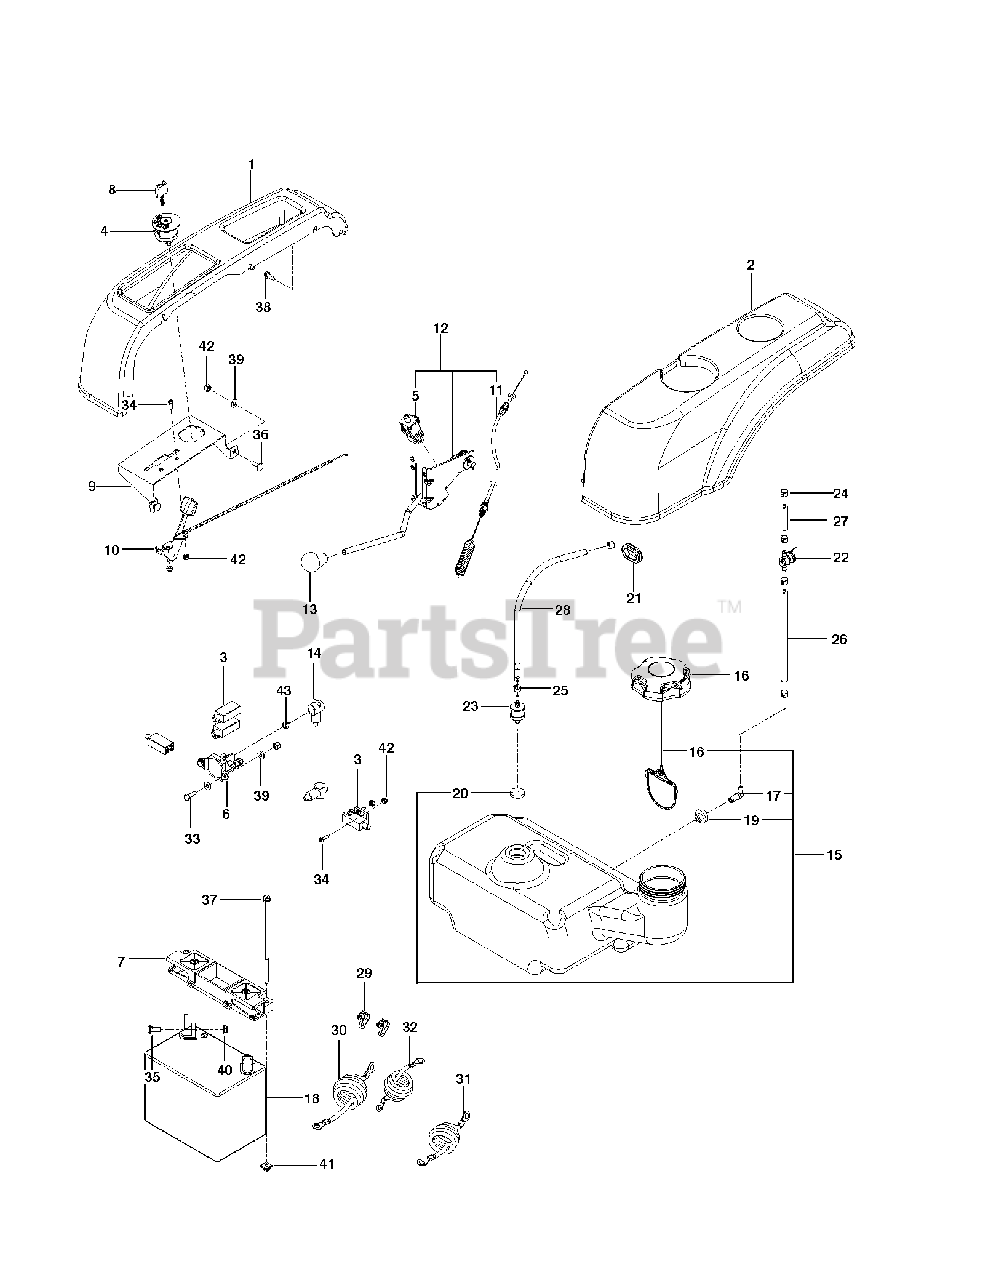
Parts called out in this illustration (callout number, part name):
1	FENDER RH
2	FENDER LH
4	IGNITION SWITCH
5	SWITCH INTERLOOK PUSH-IN
6	SOLENOID
7	BATTERY HOLD DOWN
10	THROTTLE CABLE
13	KNOB - SHIFT
14	TERMINAL COVER-SM
16	CAP, FUEL
19	RUBBER GROMMET
20	GROMMET, CHECK VALVE
22	FUEL VALVE
23	VALVE.FUEL.CHECK
24	HOSE CLAMP
25	CLAMP, HOSE
26	HOSE 1/4 X 8
27	HOSE 1/4 X 2"
28	HOSE, FUEL, 3/16" X 20"
29	TIE WRAP, 8-3/8", W/CLIP
30	POST.CABLE LONG
31	CABLE POSITIVE, LONG
32	BATTERY CABLE, NEGATIVE
33	HCS 1/4C X 3/4 HCS
34	SCREW #10-24 X 5/8
35	BOLT 5/16C X 3/4" CARRIAGE
36	RHSNB 1/4C X 3/4
37	BOLT - 1/4-20 X 7.5
38	SCREW 1/4 X 5/8
39	WASHER 1/4 SAE
40	5/16-18 NYLOC FLANGE NUT
41	PUSH NUT-NYLON
42	NUT 10-24 NYLOC
43	NUT 1/4-20 NYLOC
